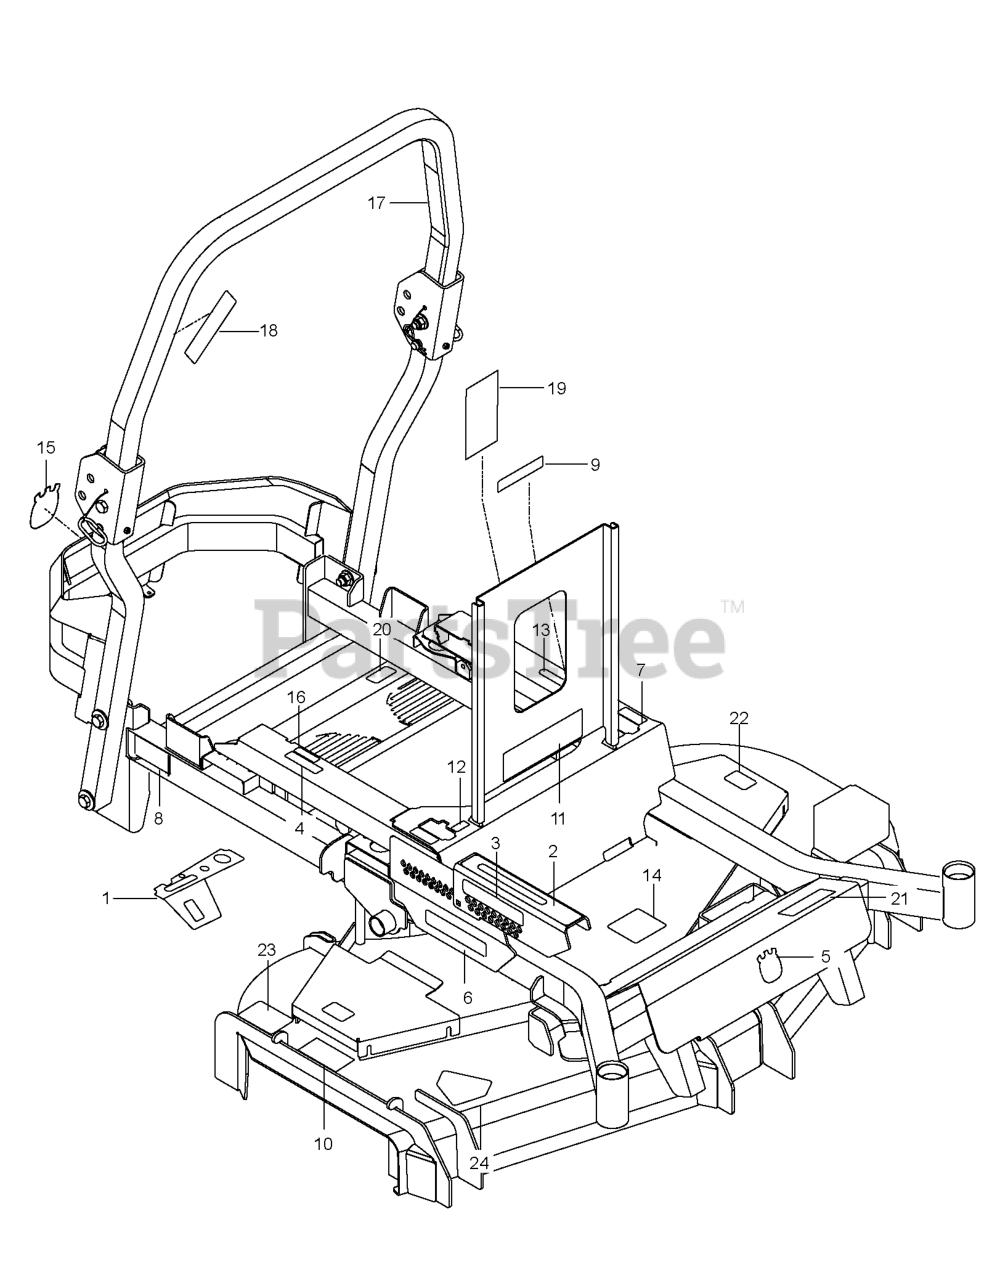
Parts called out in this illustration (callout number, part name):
1	DECAL, CONTROL, GAS
2	DECAL, HEIGHT
3	DECAL, HEIGHT
4	DECAL, WARNING SPARK ARRESTOR
5	DECAL.AUGER.HUSQ.CROWN.SNOW
6	RP.DECAL.BADGE.170MM.TEXTLOGO
7	DECAL.ZTR.MOTCONTRL.SYMBOL.HUS
8	DECAL, BELT DRIVE
9	EURO DECAL-BATTERY WARNIN6
10	DECAL, EURO SEVERING
11	DECAL.ZTR.WARNING.SMARTIGNITIN
12	DECAL.STR.S.T.SYSMBOLONLY.2014
13	DECAL, PARK BRAKE
14	DECAL, BELT ROUTING
15	DECAL, CROWN H, 110MM
16	DECAL, FUSE
17	DECAL, ROPS, WARNING
18	DECAL, ROPS
19	DECAL, SERVICE
20	DECAL, FUEL
21	DECAL.ZTR P272.HUSQ
22	DECAL.DECK.6MIL.EURO.NOSTEP
23	DECAL.DECK.6MIL./DEF.SHLD.WARN
24	DECAL, DECK DEFLECTOR, WARNING
